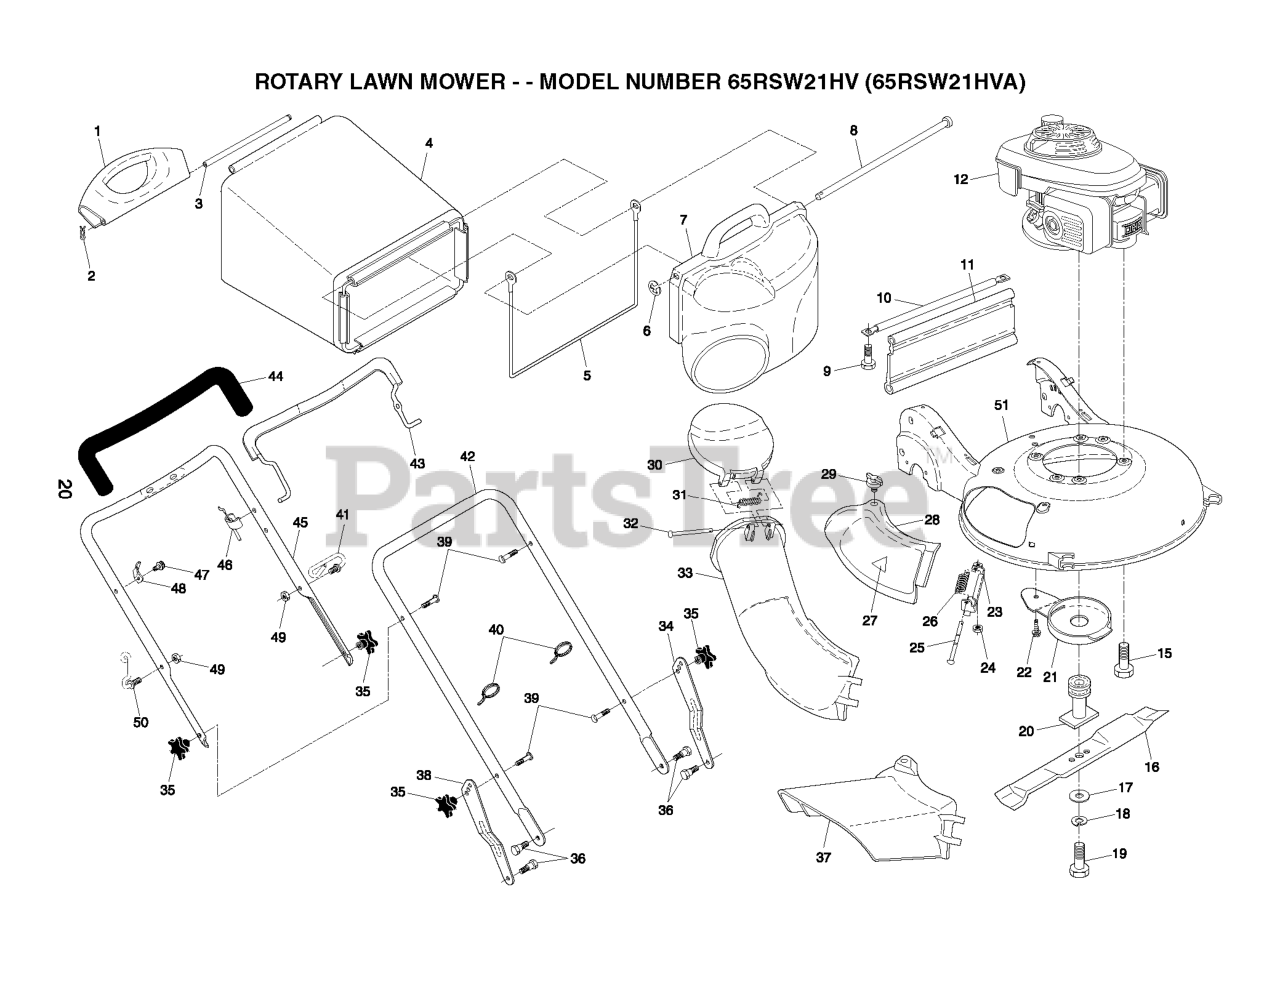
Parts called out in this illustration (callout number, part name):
1	HANDLE, GRASSBAG, REAR
2	COTTER PIN (3 2)(2 2MC)
3	ROD.REAR.HANDLE.YELLOW
4	GRASSBAG
5	GRASSBAG FRAME
7	DOOR, GRASSBAG
8	ROD, PIVOT
9	SCREW.HWH.13-16X1.12
11	SKIRT.REAR.21".HI-VAC.BLACK
15	BOLT 3/8-16X1-1/8
16	21" MULCH BLADE PREMIUM
17	WASHER,HARDEN
18	LOCKWASHER
19	SCREW.HX.HEAD.3/8-24
20	ADAPTER, BLADE
21	DEBRIS SHIELD
22	SCREW 1/4X20
23	BRACKET.ASM.HINGE
24	LOCK NUT
25	ROD.HINGE.1/4"3.82"
26	SPRING.MULCH.DOOR
27	DECAL HYT
28	MULCH DOOR
29	KNOB.MULCH.DOOR
30	DOOR, DICHSRGE CHUTE
32	ROD.HINGE.1/4"3.82"
33	PLASTIC DISCHARGE CHUTE
33	CHUTE ASSY
34	BRACKET
35	KNOB.HANDLE.STAR.HUSQ.GRAY
36	SHOULDER BOLT
37	GUARD.CLIP.ON.21.HV.GRAY
38	BRACKET ADJ LOWER HNDLE RH
39	HANDLE BOLT
40	TIE GUIDE
41	BRACKET.ANTIFOLD.HI-VAC(ONLY)
42	HANDLE.LOWER.GREY
43	BAIL CONTROL
44	GRIP.HANDLE.FOAM.WIDE.(1 SIDE)
45	HANDLE.ASM.UPPER.W/GRIP
46	ASSY ZONE CONTROL
48	BRACKET
50	ROPE GUIDE
51	KIT.HSG.ASM.21".CASTER
